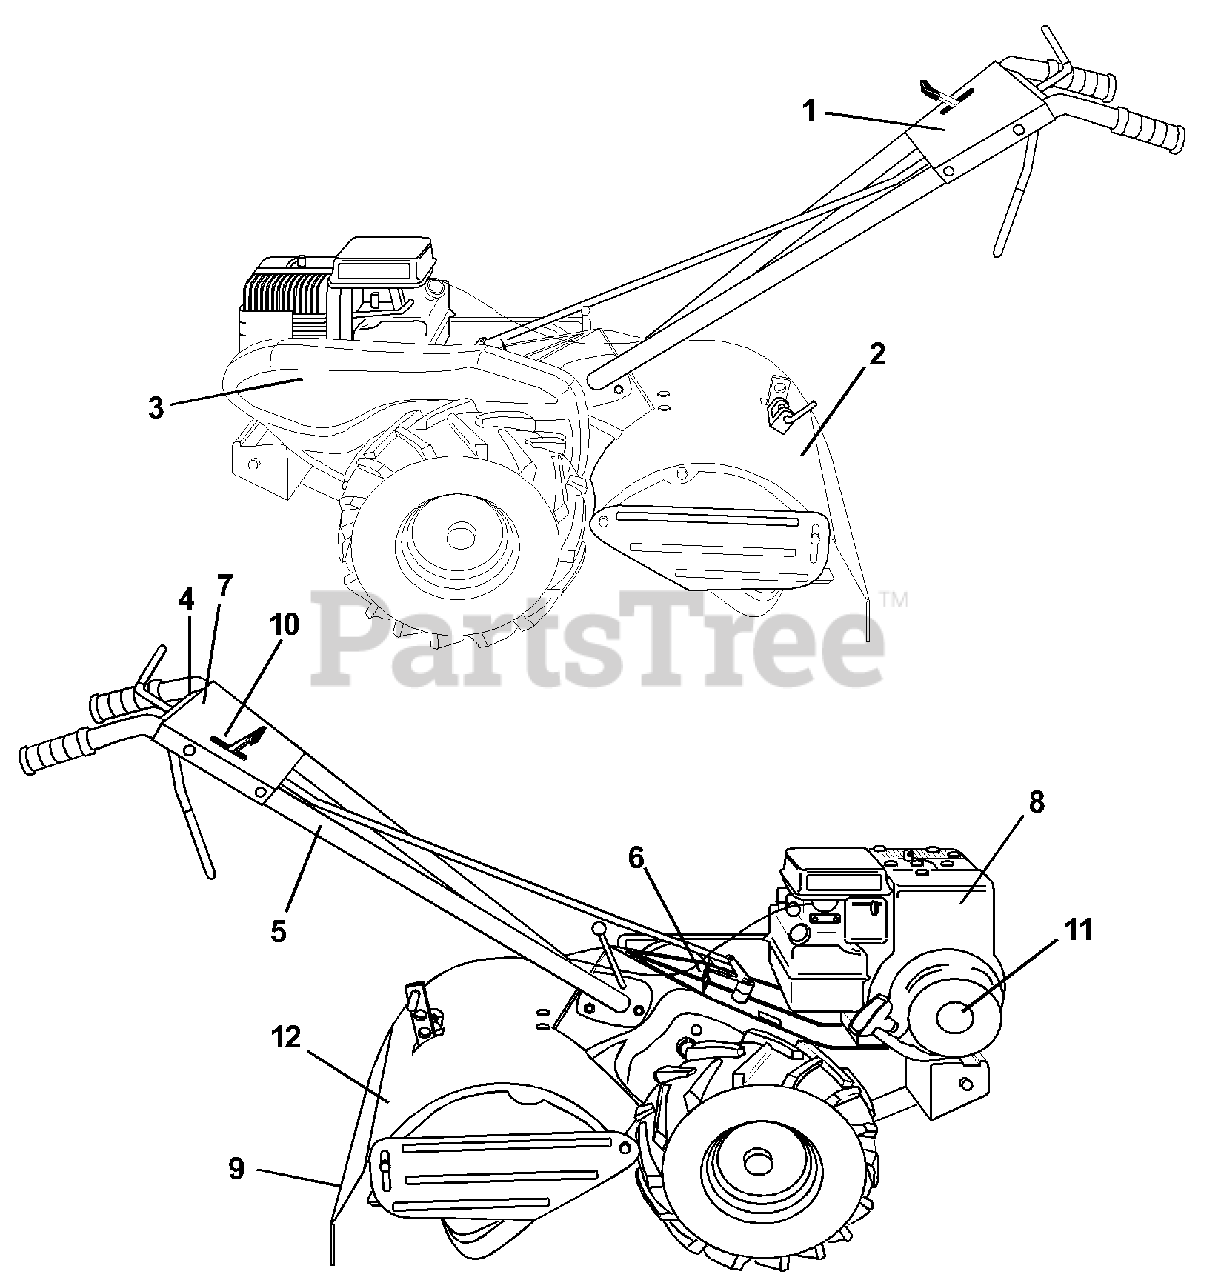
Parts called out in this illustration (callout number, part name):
1	Decal, Logo
2	Decal, Logo
3	Decal, Logo
4	Decal, Instruction, Tilling
5	Decal, Hand Placement
6	Decal, Shift Indicator
7	Decal, Pnl Cntrl Reverse
8	Decal, Briggs & Stratton
9	Decal, Warning, Rotating Tines
10	Decal, Throttle
11	Decal, 5 HP
12	Decal, Warning Till
